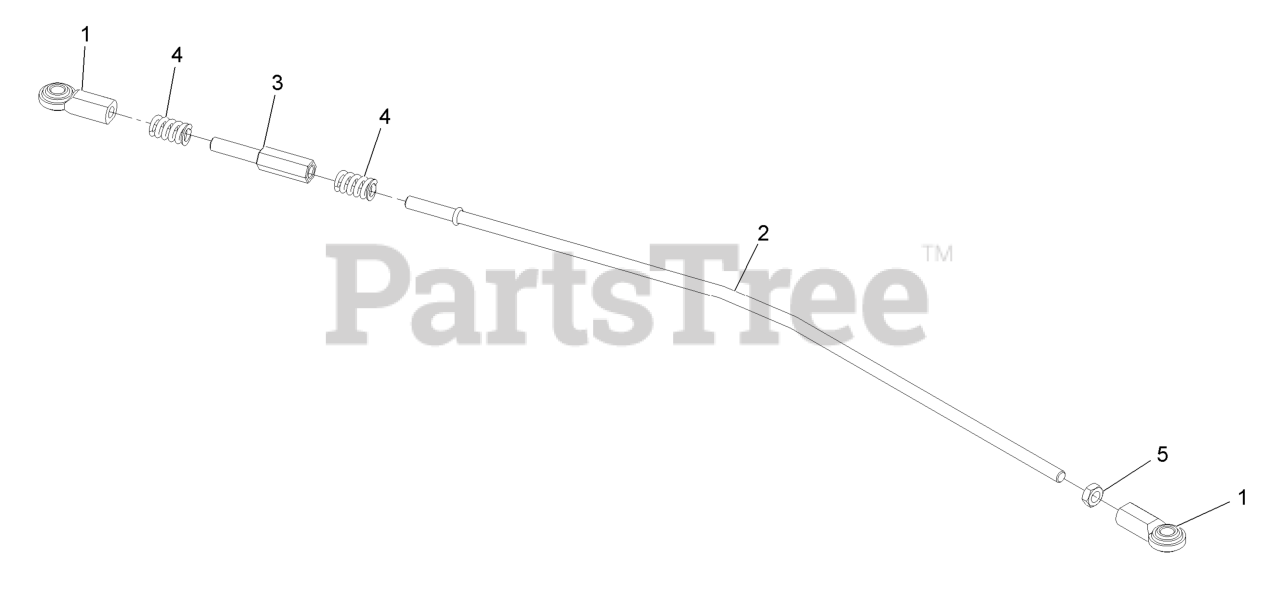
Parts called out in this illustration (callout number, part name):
1	JOINT-BALL, END
2	LINK-LOWER, MOTION CONTRO
3	ROD-ADJUSTMENT
4	SPRING, COMPRESSION
5	NUT-HJ
